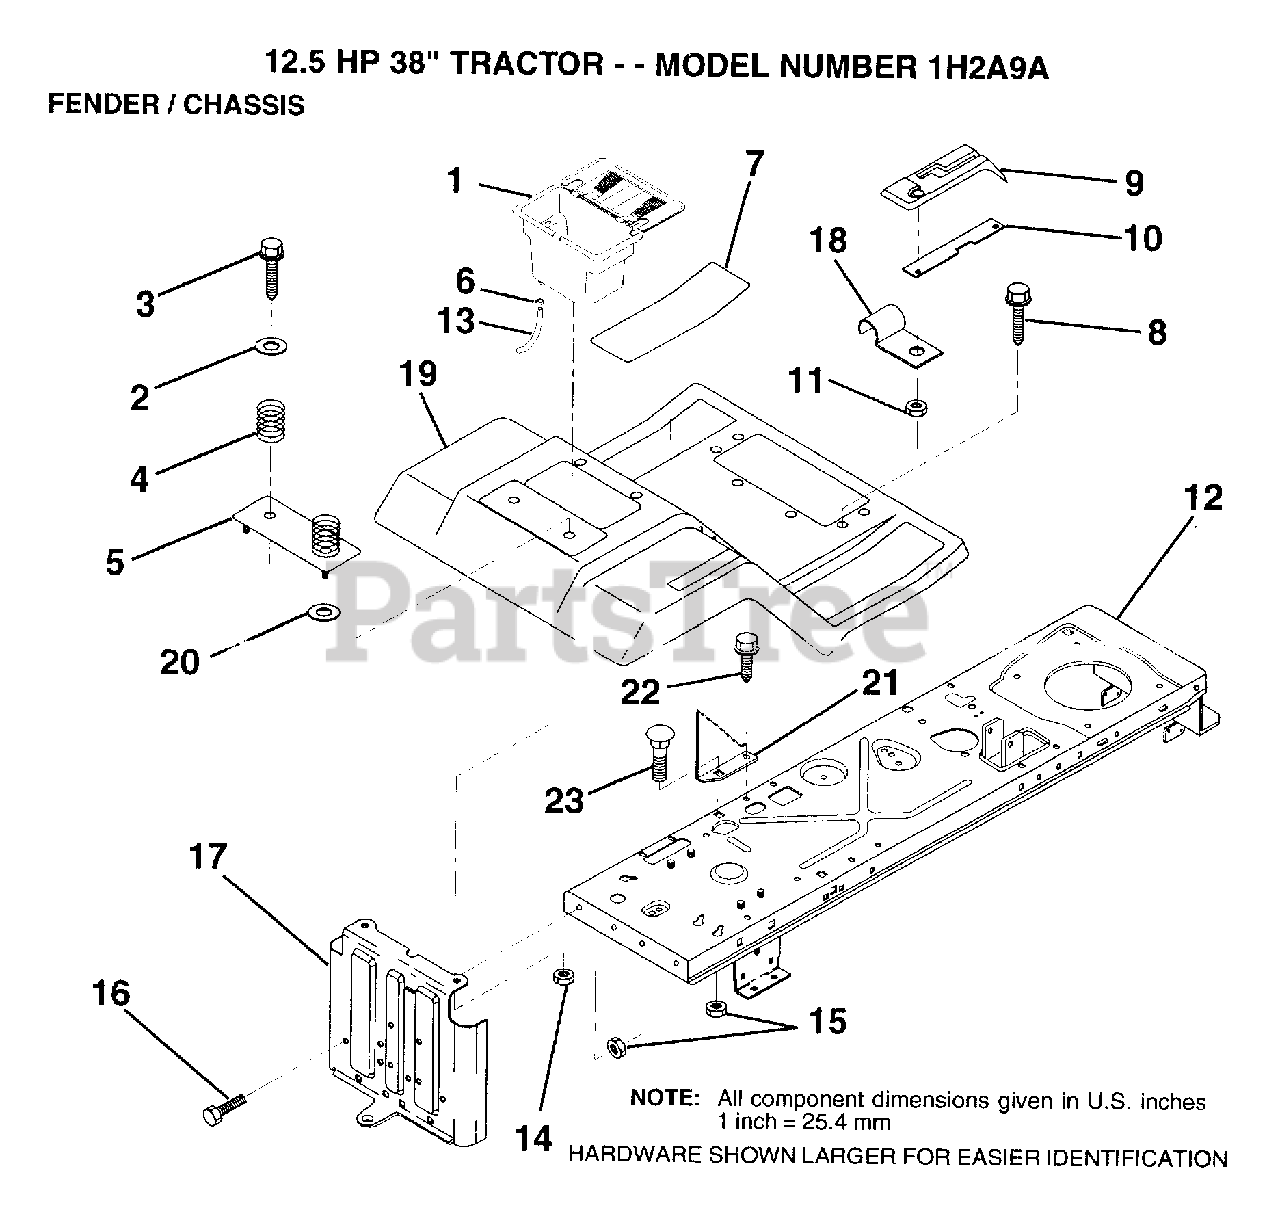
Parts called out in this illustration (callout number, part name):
2	WASHER
3	SCREW
4	SPRING COMPRESSIO
5	BTRY FENDER PLATE
6	HOSE CLAMP T
7	PAD FOOTREST
8	SCREW
10	"SHIFT LOCK, BAR"
11	NUT
13	TUBE T
14	NUT
16	BOLT
17	DRAWBAR
18	"CLIP,INSULATOR"
22	SCREW LT
